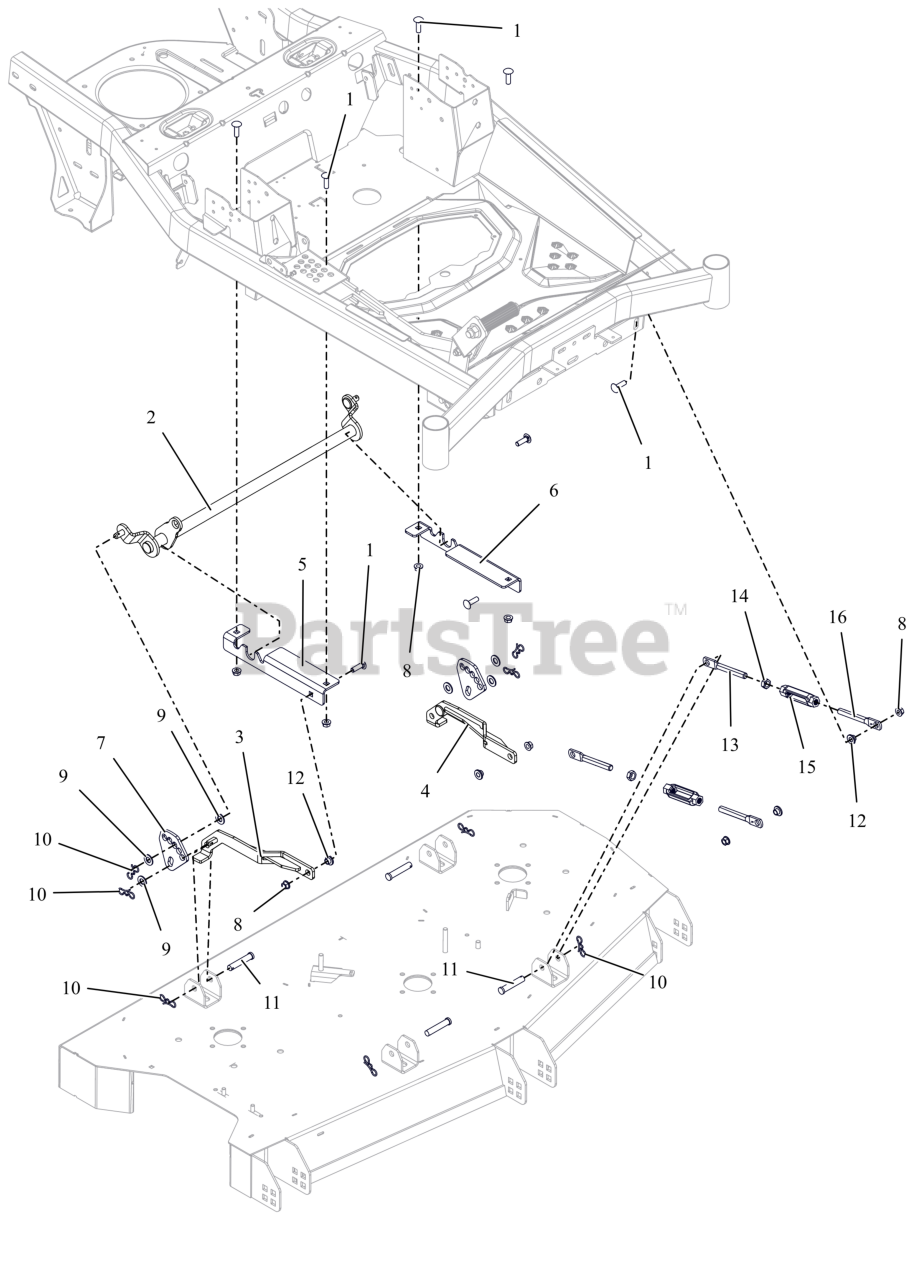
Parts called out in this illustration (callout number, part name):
1	BLT,RHSSN .38-16X1.25 G5 ZCC
2	WLDMT- DECK LIFT SHAFT
3	WLDMT- REAR DECKLIFT -RH
4	WLDMT- REAR DECKLIFT BRKT-LH
5	PLATE- REAR DECKLIFT MTG-RH
6	PLATE- REAR DECKLIFT MTG-LH
7	BRKT- DECK HEIGHT ADJUSTER
8	NUT-LK-CTR-FLG .375-16 GF ZCC
9	WSHR-FL-NYL .518X1.000X.080
10	PIN, BOWTIE .091X1.875 ZCC
11	PIN-CLEV .494X2.50 BRIGHT ZINC
12	BSHG-FLG .385X.500X.875X.406
13	LINK- DECK -RH
14	NUT-JAM .500-13 G2 ZCC
15	TURNBUCKLE- STEEL 1/2-13
16	ROD, FRONT LIFT - LH THREAD
